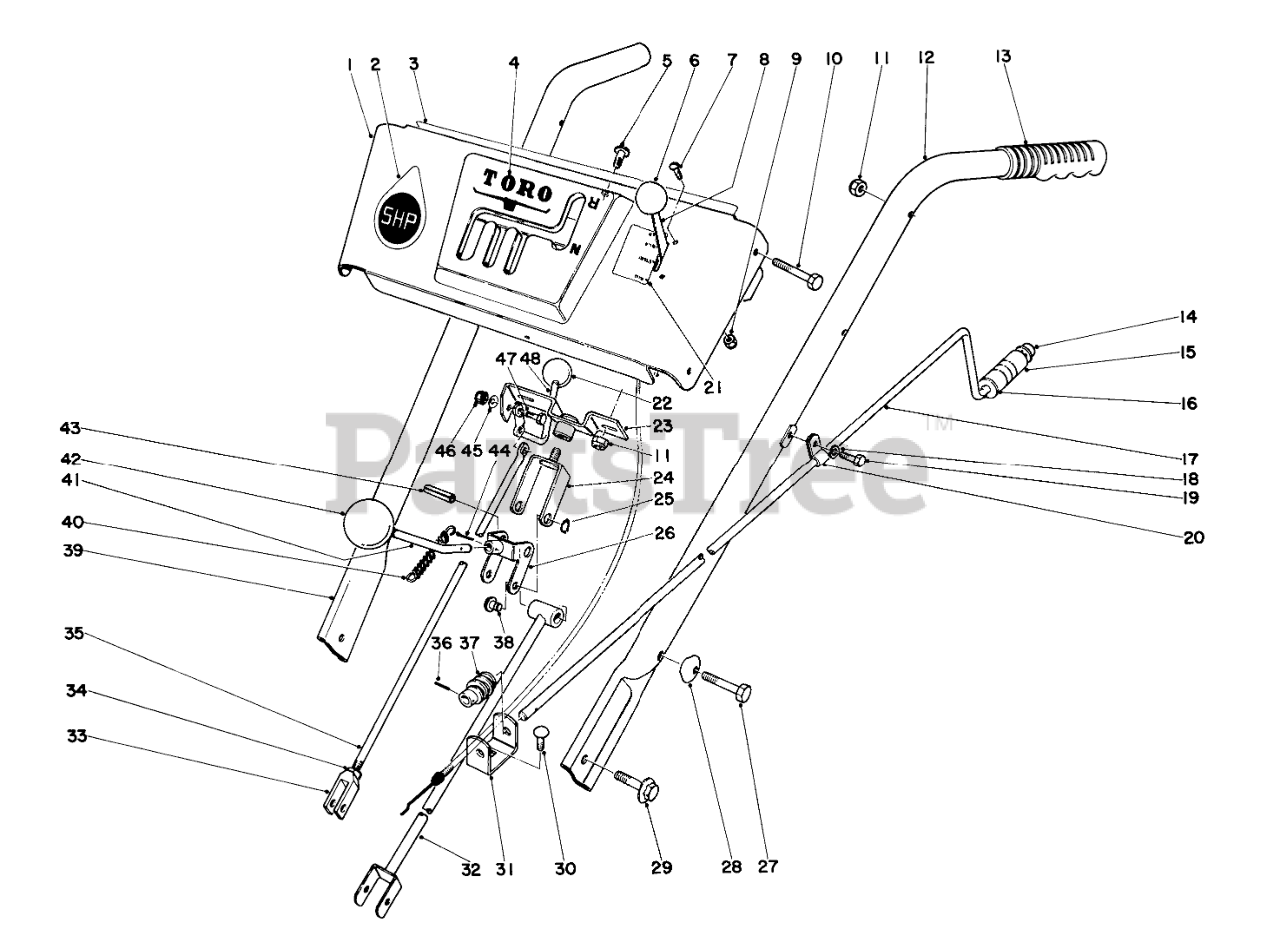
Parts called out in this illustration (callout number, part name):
1	Escutcheon Plate (Incl. Ref. Nos. 2, 3, 4 & 21)
2	Decal, 5 H.P.
3	Decal, Escutcheon Back
4	Decal, Escutcheon
5	Screw, Machine
6	KNOB-CONTROL
7	SCREW-PPH
8	Control-Throttle
9	Nut
10	SCREW-HH
11	NUT-LOCK
12	Left Handle
13	Grip Handle
14	Speed Nut
15	Chute Control Grip
16	WASHER-FLAT
17	ROD CHUTE CONTROL
18	SCREW-HH
19	WASHER-LOCK
20	R-CLAMP
21	Decal, Throttle
22	Knob
23	SWIVEL BLOCK WA
24	Pivot Bracket
25	Ring-Snap
26	Control Bracket
27	SCREW-HH
28	Curved Washer
29	SCREW-HHF
30	SCREW-CARR
31	Bracket Worm
32	Trunnion
33	Yoke
34	NUT-HJ
35	Drag Link
36	PIN-SPRING
37	GEAR-WORM, CHUTE
38	Pin Shift Lever
39	Handle, R.H.
40	CONT ROD SPRING 0
41	Shift Rod
43	PIN-ROLL
44	PIN-COTTER
45	Lynch Pin
46	NUT-LOCK
47	SCREW-HH
48	Handle, Auger Shaft
